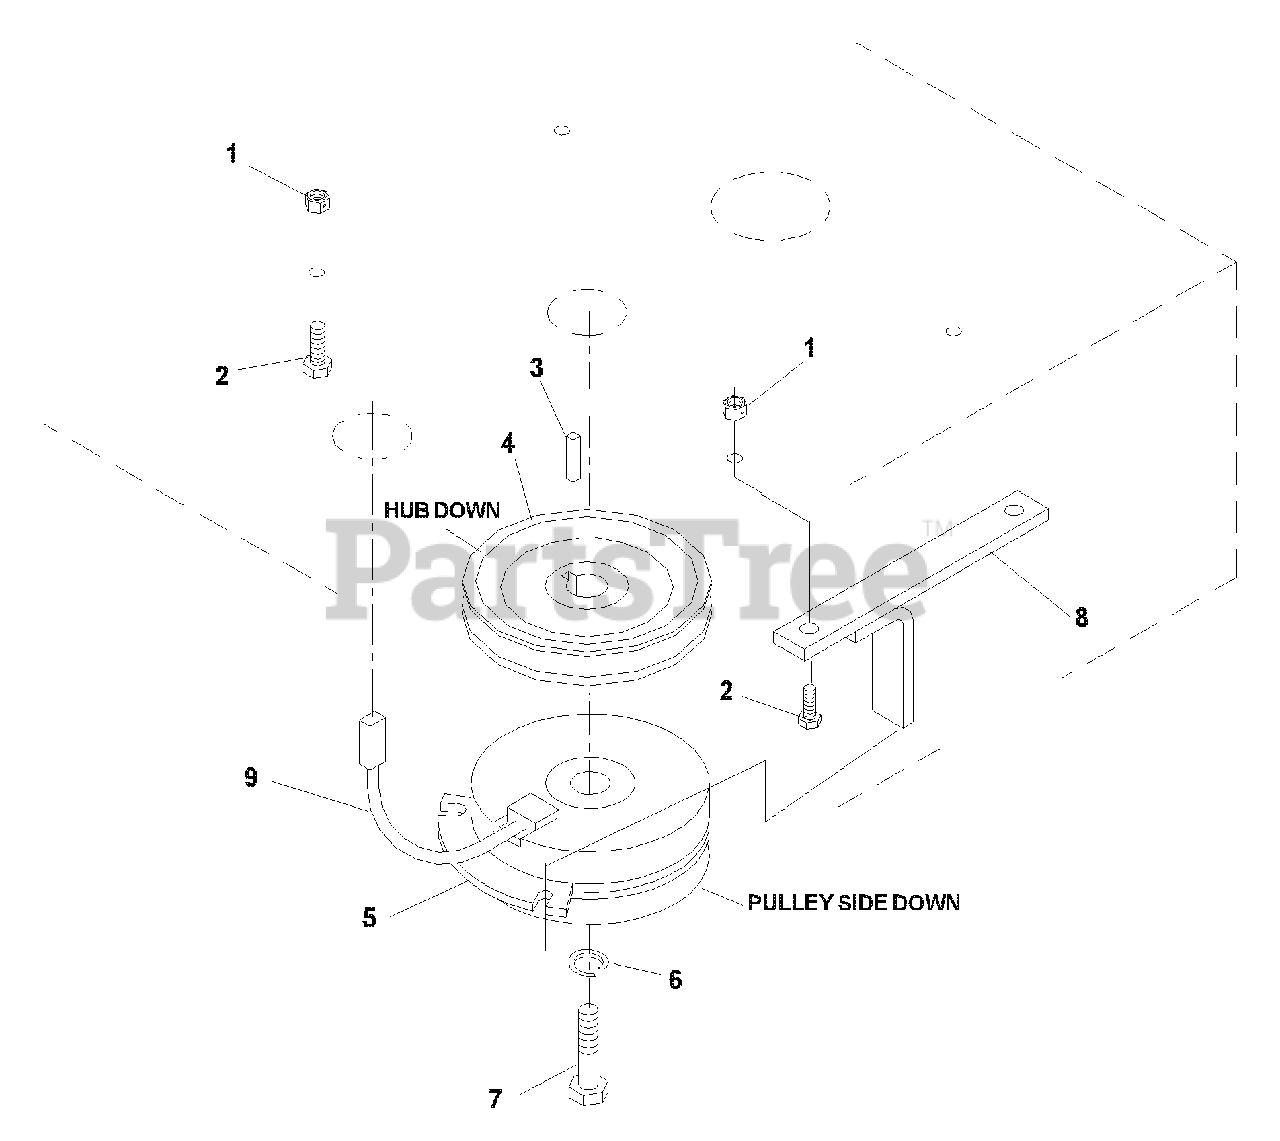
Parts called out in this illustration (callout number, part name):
1	NUT 5/16C NYLOC
2	HCS 5/16C X 1 3/4
3	KEY 1/4 SQ. X 1 1/4
5	CLUTCH, 200 FT/LB
6	7/16 LOCKWASHER
7	HCS 7/16F X 2 1/2
8	CLUTCH TIE DOWN
9	WIRING HARNESS
